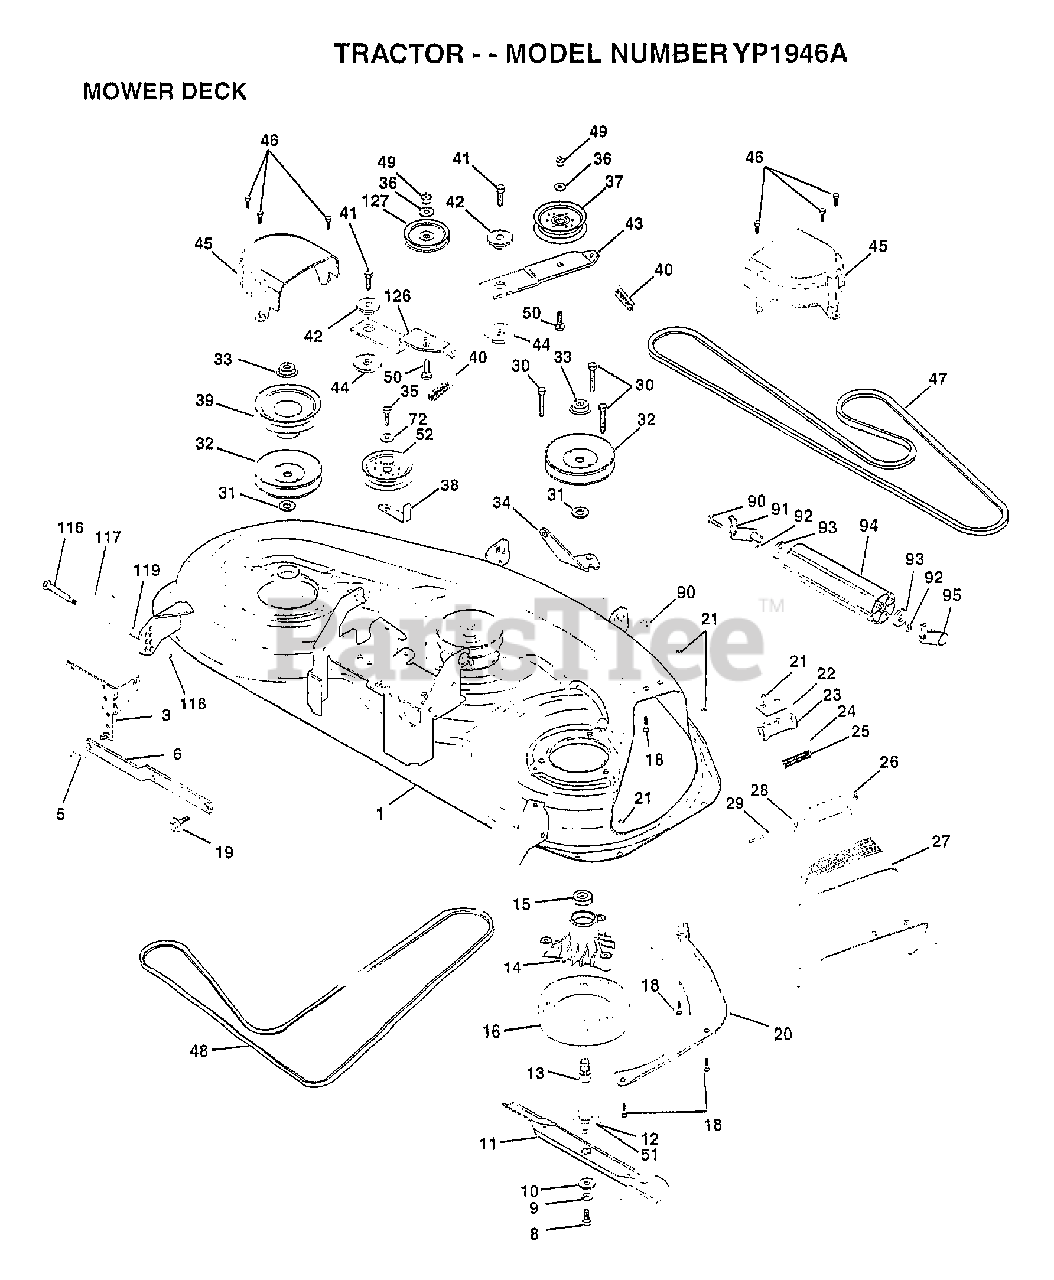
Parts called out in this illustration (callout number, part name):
1	"MOWER ASM 46"""
3	BRKT.ASM.SW.44/50
8	BLADE BOLT
10	WASHER.HARD.BLADE
12	BEARING.BALL
13	SHAFT.ASM.W/BRNG
14	HOUSING.MAND.44.V
15	BEARING
16	STRIPPER RND MWR
18	BOLT
19	BOLT SHD 5/16-18
20	BAFFFLE.VORTEX.46
22	STIFFENER BRKT
23	DEFLECTOR BRKT
24	CAP-SLEEVE LT
25	SPRING TORSION
26	NUT PUSH M
27	SHIELD DEFLECTOR
28	WASHER
29	HINGE ROD
31	WASHER
32	PULLEY.MAND.36/46
34	ANCHOR.SPRING.46
35	SCREW LT
36	WASHER
37	FLAT IDLER PULLEY
38	"KEEPER BELT,IDLER"
39	PULLEY.DRV.DCK.46
40	"SPRING.SEC.44""VEN"
41	SCREW
42	SPACER RETAINER
43	ARM.IDLER.DECK.46
44	HARDENED WASHER
45	COVER.MANDREL.46
46	SCREW.1/4-20X5/8
47	BELT-V.SEC.46.KEL
48	BELT V PRIM 50
50	BOLT.3/8-16X1.50
51	WASHER.FELT.
52	"PULLEY IDLER,FLAT"
72	WASHER HYT
90	BOLT
92	NUT
93	WASHER
116	BOLT.SHOULDER
117	WHEEL GAGE DONUT
118	LOCKNUT
119	WASHER
126	ARM.IDLER.PRIM.46
127	PULLEY.IDLER.4.25
